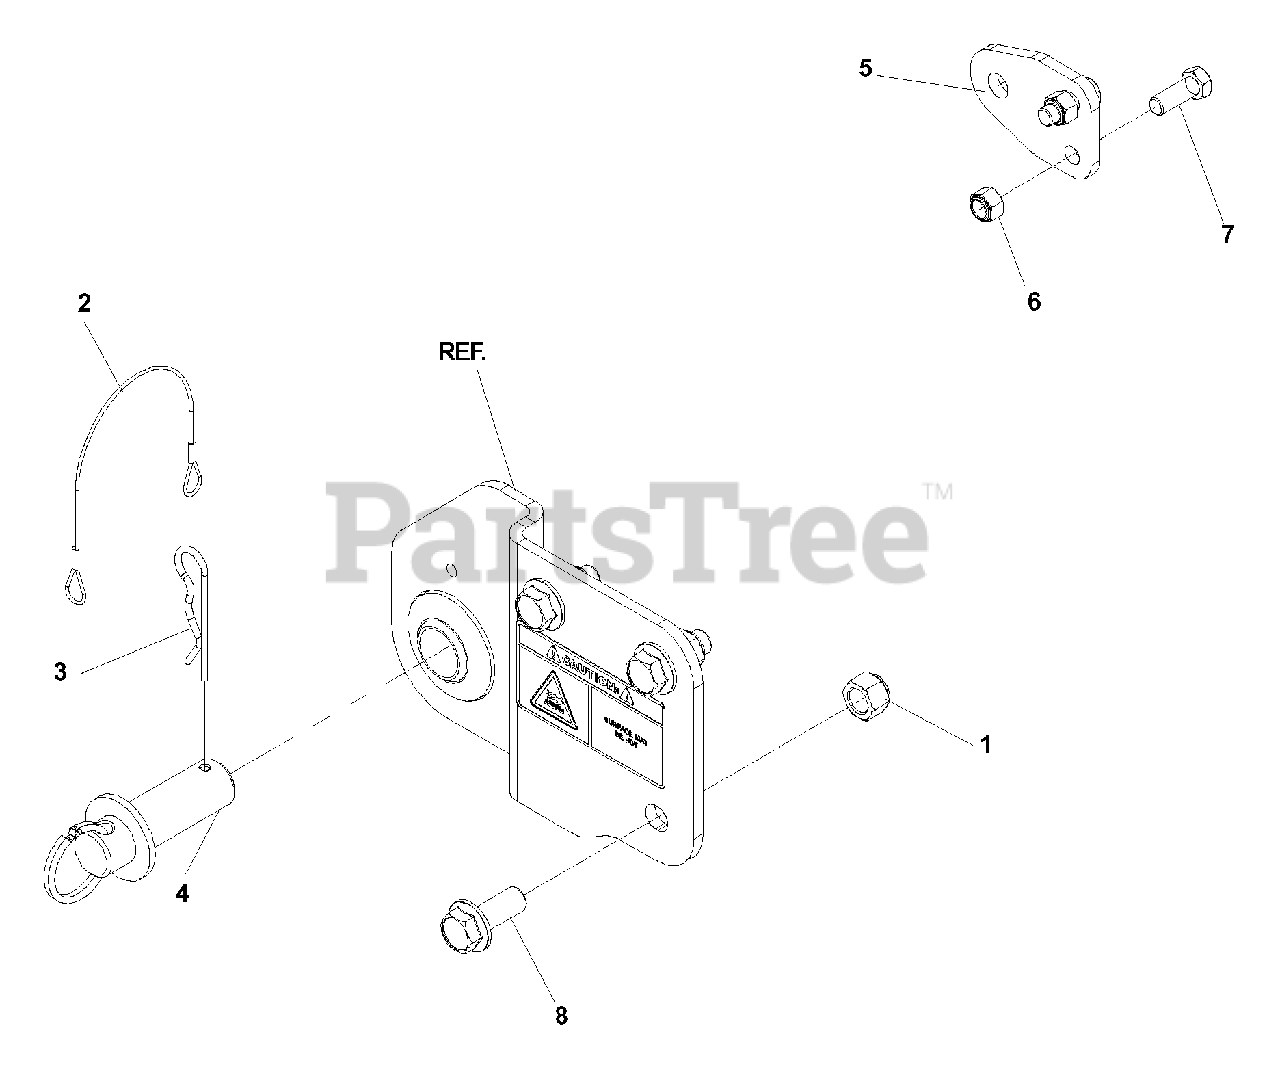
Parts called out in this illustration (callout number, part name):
1	NUT, 1/2 -13, NYLOC
5	SUPPORT BRACKET
6	NUT, 3/8 -16, NYLOC
7	HCS, 3/8 -16 x 1,
8	BOLT, 1/2 -13 x 1 1/4, WHIZLK
